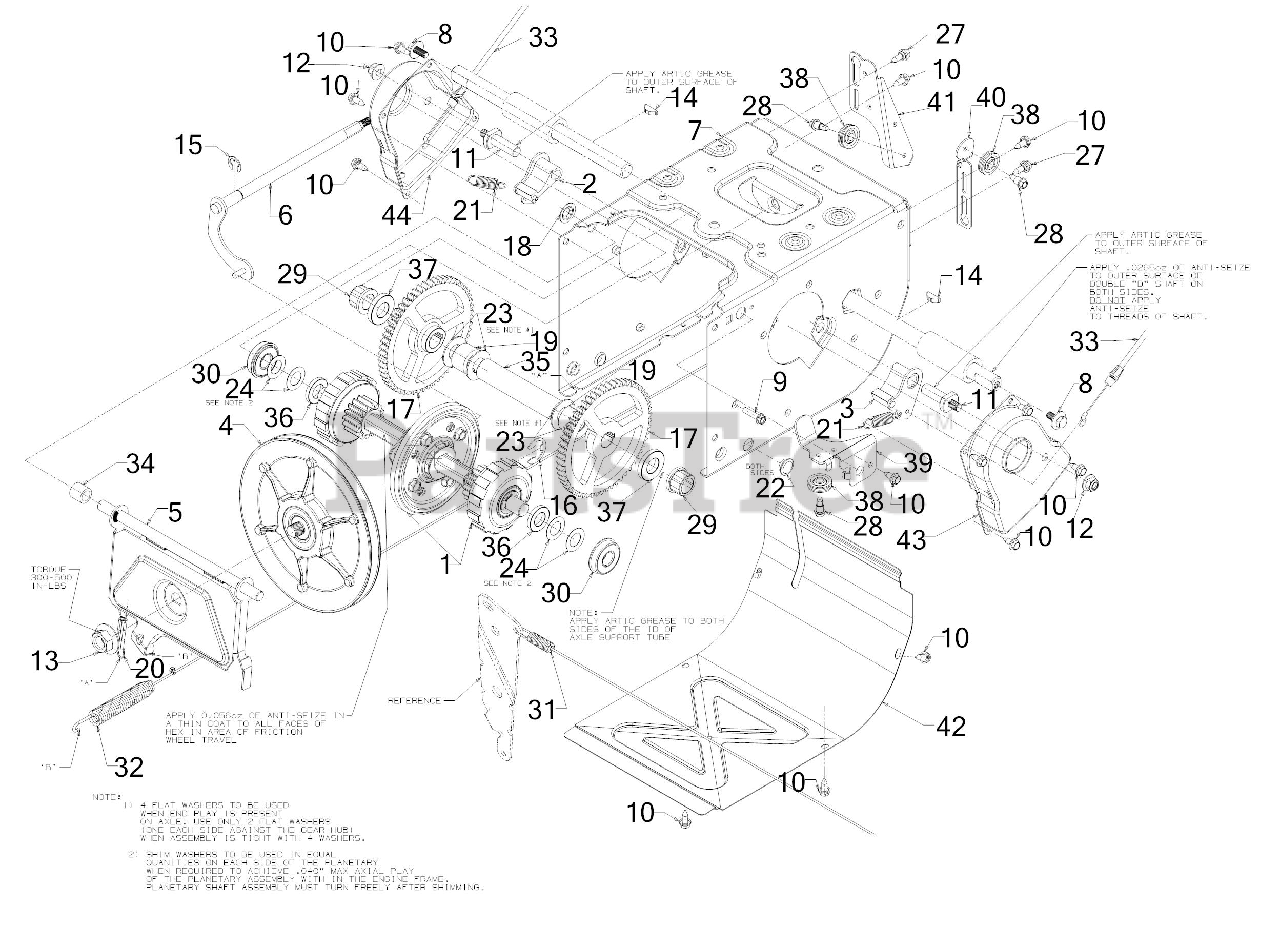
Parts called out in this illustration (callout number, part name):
1	PLANETARY SHIFT ASSEMBLY
1	PLANETARY CARRIER ASSEMBLY
1	FRICTION WHEEL ASSEMBLY
2	DOGG ASSEMBLY (RH)
3	DOGG ASSEMBLY (LH)
4	FRICTION WHEEL DISC ASSEMBLY
5	FRICTION WHEEL BRACKET
6	SHIFT ROD ASSEMBLY
8	SCREW 5/16-24 x .750 GR5
9	SCREW 1/4-20 x 1.00
10	SCREW 1/4-20X.625
11	ACTUATOR SHAFT
13	FLANGE NUT 5/8-18
14	KEY 3/16 x 3/4
15	E-RING FOR .500
16	RETAINING RING
17	GEAR-56T
18	PUSH CAP
19	SPACER: .76ID x .75
20	EXTENSION SPRING
21	EXTENSION SPRING
22	HOLE PLUG
23	FLAT WASHER .760ID X1.49OD x .06
24	FLAT WASHER .67X 1.174X .02
27	SHOULDER SCREW
28	SHOULDER SCREW
29	FLANGE BEARING
30	BALL BEARING
31	AUGER DRIVE CABLE 47.48"
32	WHEEL DRIVE CABLE 44.955"
33	STEERING CABLE
34	SPACER-.513 ID x .703 OD x .69
35	AXLE SUPPORT TUBE
36	SPACER
37	AXLE SPACER
38	CABLE GUIDE ROLLER
39	AUGER CABLE BRACKET
40	AUGER CABLE GUIDE BRACKET
41	GUIDE BRACKET
